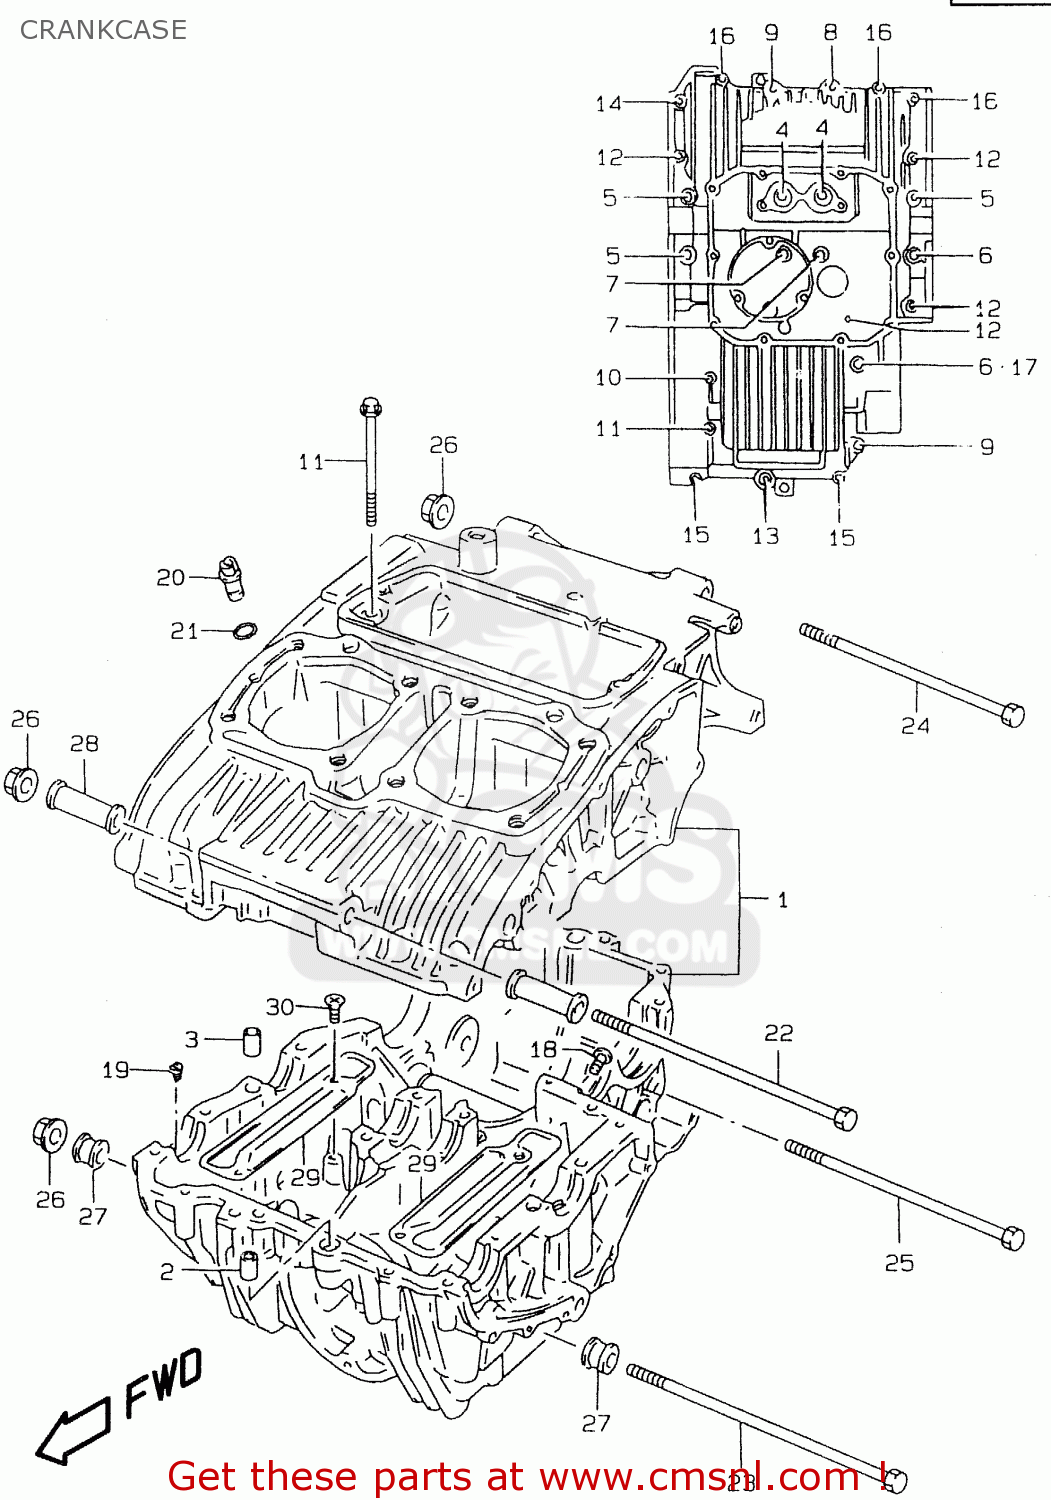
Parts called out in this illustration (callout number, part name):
1	CRANKCASE SET
2	PIN(10.4X13X22)
3	PIN(8.4X11X20)
4	BOLT
5	BOLT(8X125)
6	BOLT(8X110)
7	BOLT(8X100)
8	BOLT
9	BOLT
10	BOLT(6X125)
11	BOLT(6X105)
12	BOLT (6X90)
13	BOLT
14	BOLT
15	BOLT
16	BOLT (6X45)
17	GASKET 8.2X14X1 (NAS)
18	JET,AIR
19	JET
20	JET
21	O RING(D:1.05,ID:3.1)
22	BOLT(10X255)
23	BOLT(10X240)
24	BOLT(10X170)
25	BOLT(10X160)
26	NUT
27	SPACER,ENG MTG(L:16.8)
28	SPACER,ENGINE MOUNT(L:65)
29	PLATE,OIL SEPARATOR
30	SCREW
